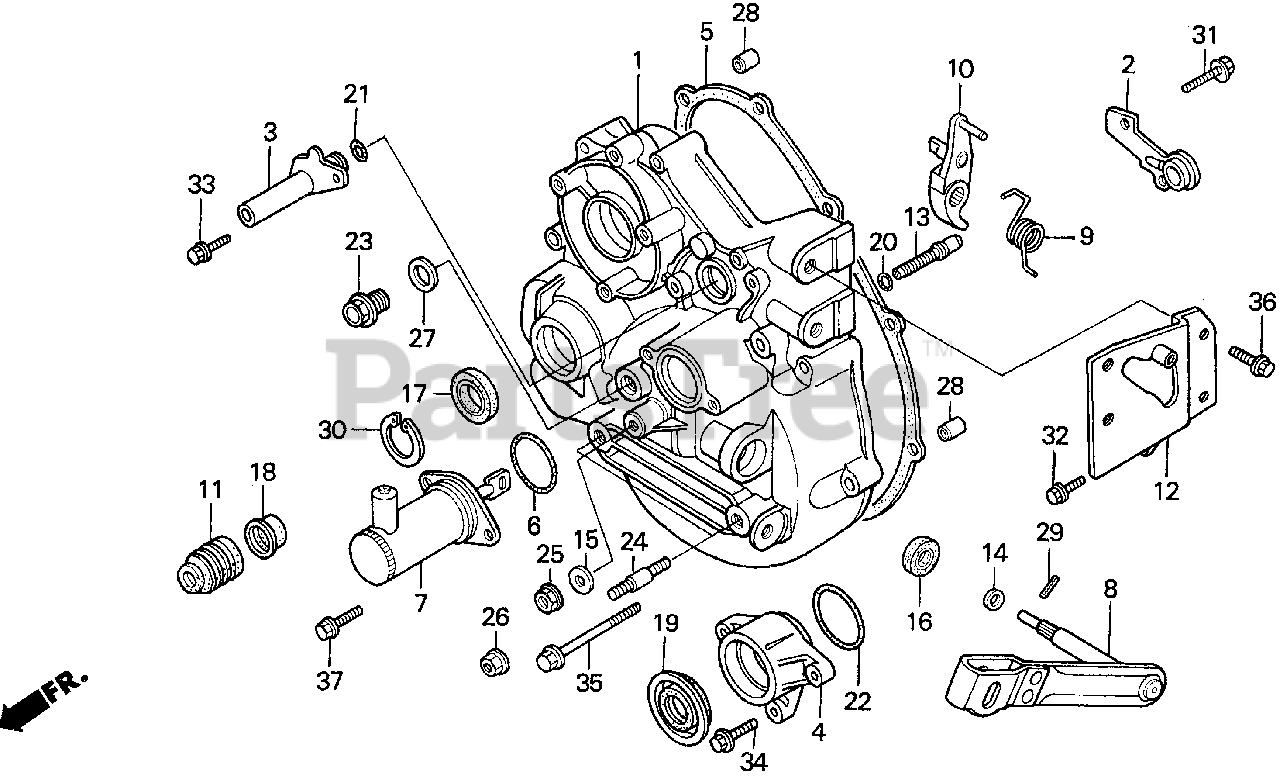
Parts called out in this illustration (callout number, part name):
1	COVER, CLUTCH
2	PLATE, OIL GUIDE
3	HOLDER, SHIFT PIECE SHAFT
4	COVER (2/4WD)
5	GASKET, CLUTCH COVER
6	O-RING (37.5X2)
7	DAMPER ASSY., CLUTCH
8	LEVER, CLUTCH
9	SPRING, CLUTCH LEVER
10	CAM, CLUTCH LIFTER
11	BOOT, SHIFT SHAFT
12	BRACKET, CHANGE LEVER HOLDER
13	BOLT, ADJUSTING (8MM)
14	WASHER, THRUST (10X16)
15	WASHER (8MM)
16	OIL SEAL (14X24X6) (ARAI)
17	OIL SEAL (22X34X7) (ARAI)
18	OIL SEAL (14X24X11.5)
19	OIL SEAL (22X45X8) (NOK)
20	O-RING (6.8X1.9)
21	O-RING (21.5X1.5)
22	O-RING (41.5X2)
23	BOLT, DRAIN PLUG (14MM)
24	BOLT, STUD (10X25)
25	NUT, FLANGE (8MM)
26	NUT, FLANGE (10MM)
27	WASHER, DRAIN PLUG (14MM)
28	PIN, DOWEL (10X16)
29	PIN, SPRING (3X16)
30	CIRCLIP (INNER) (34MM)
31	BOLT, FLANGE (6X16)
32	BOLT, FLANGE (8X20)
33	BOLT, FLANGE (8X22)
34	BOLT, FLANGE (8X28)
35	BOLT, FLANGE (8X55)
36	BOLT, FLANGE (10X25)
37	BOLT, FLANGE (6X16)
